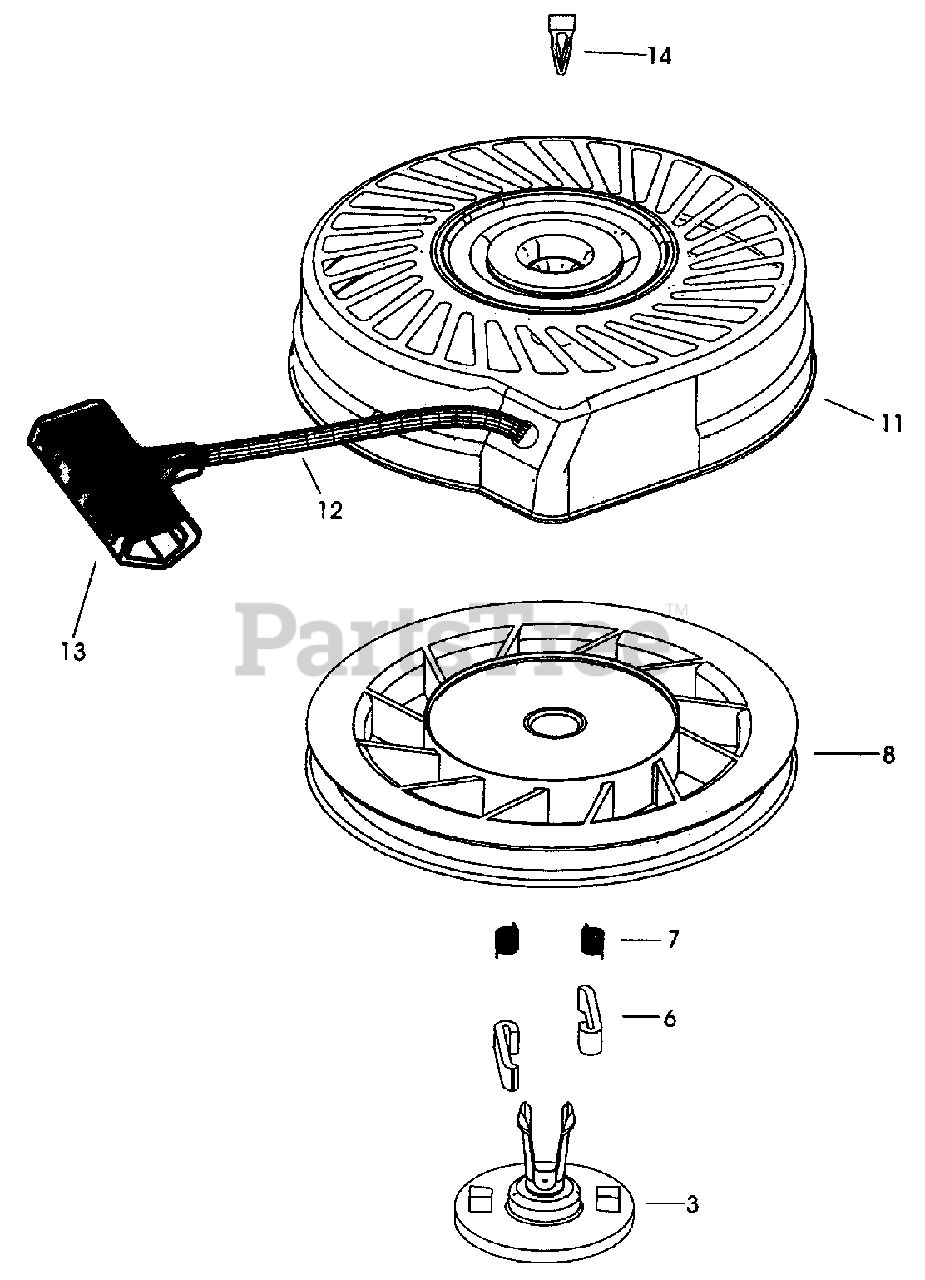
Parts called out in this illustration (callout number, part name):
3	Retainer
6	Starter Dog
7	Dog Spring
8	Pulley & Rewind Spring Ass'y
11	Starter Housing Ass'y (40 degree grommet)
12	Starter Rope (Length 98" x 9/64" dia.)
13	Starter Handle
14	Locking Tab
